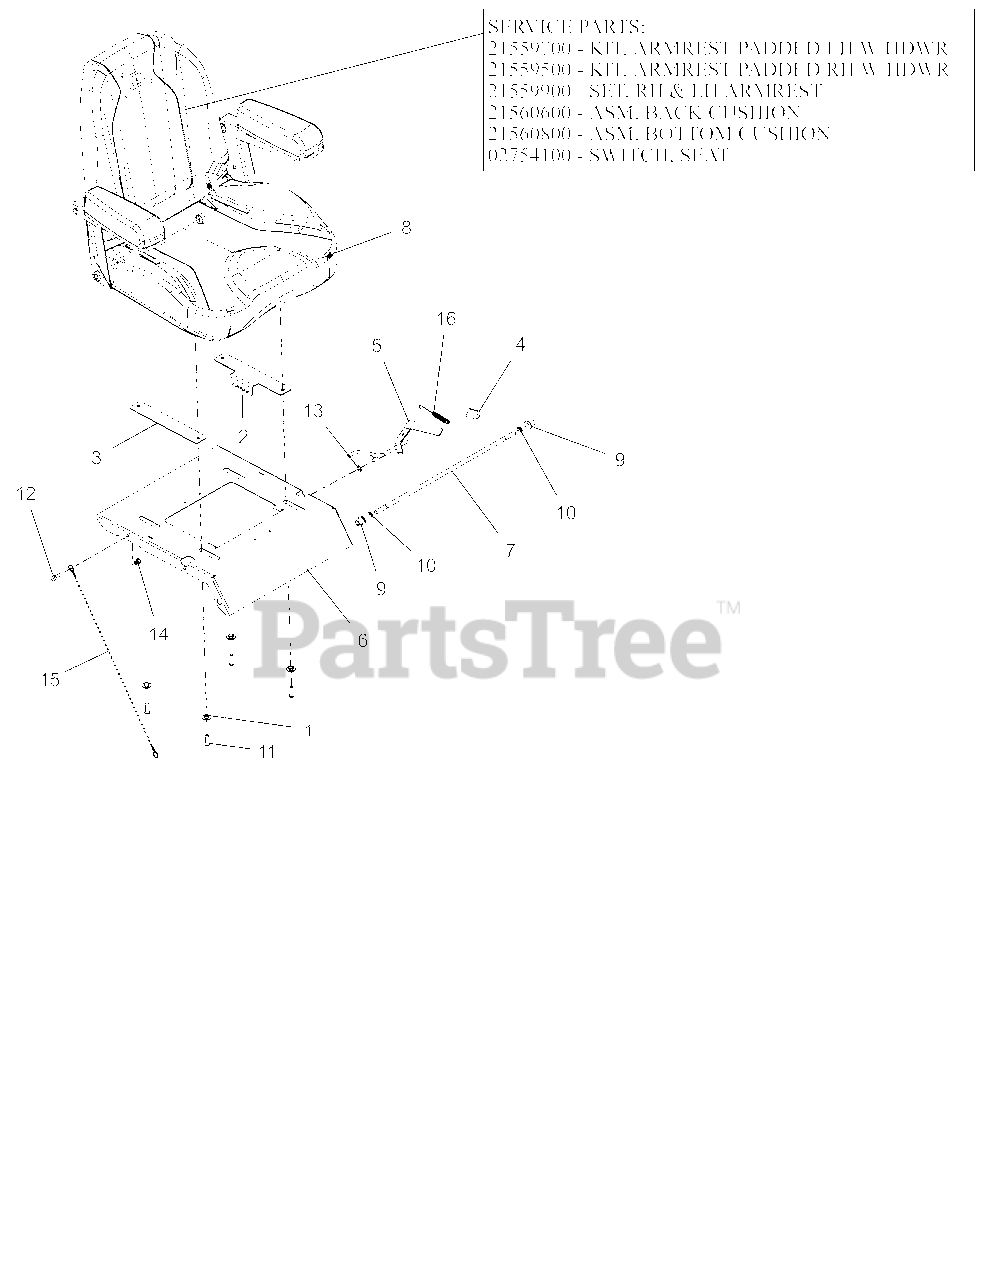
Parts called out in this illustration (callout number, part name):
1	BSHG, FLG .325X.499X.26X.88
2	PLATE, ADJUSTABLE SEAT TRACK
3	PLATE, ADJUSTABLE SEAT SLIDE
4	GRIP, SEAT LEVER, GREY
5	WLDMT, ADJUSTABLE SEAT LATCH
6	PLATE, SEAT
7	ROD, SEAT PIVOT
8	SEAT, ZTXL 2017
8	PAD, LH ARMREST
8	PAD, RH ARMREST
8	SET, RH & LH ARMREST ASM
8	ASM, BACK CUSHION-GRAVELY XL
8	ASM,BOTTOM CUSHION-GRAVELY XL
8	SWITCH- SNAP MTG N.O.
9	BSHG-FLG .38X.580X.667X.750
10	RG-RTNG-EXT .375X.035 TYP E
11	SCR-SKH .31-18X1.0 BTNHD YWZC
12	BLT,HEX-FLG .25-20X.75 G5 BFP
13	NUT-PUSH .312
14	@NUT-LK-NYL-FLG .31-18 YWZC
15	LANYARD, SEAT CABLE .093X19.5
16	SG-TENS .043X.44X3.31 WLD 5.8
